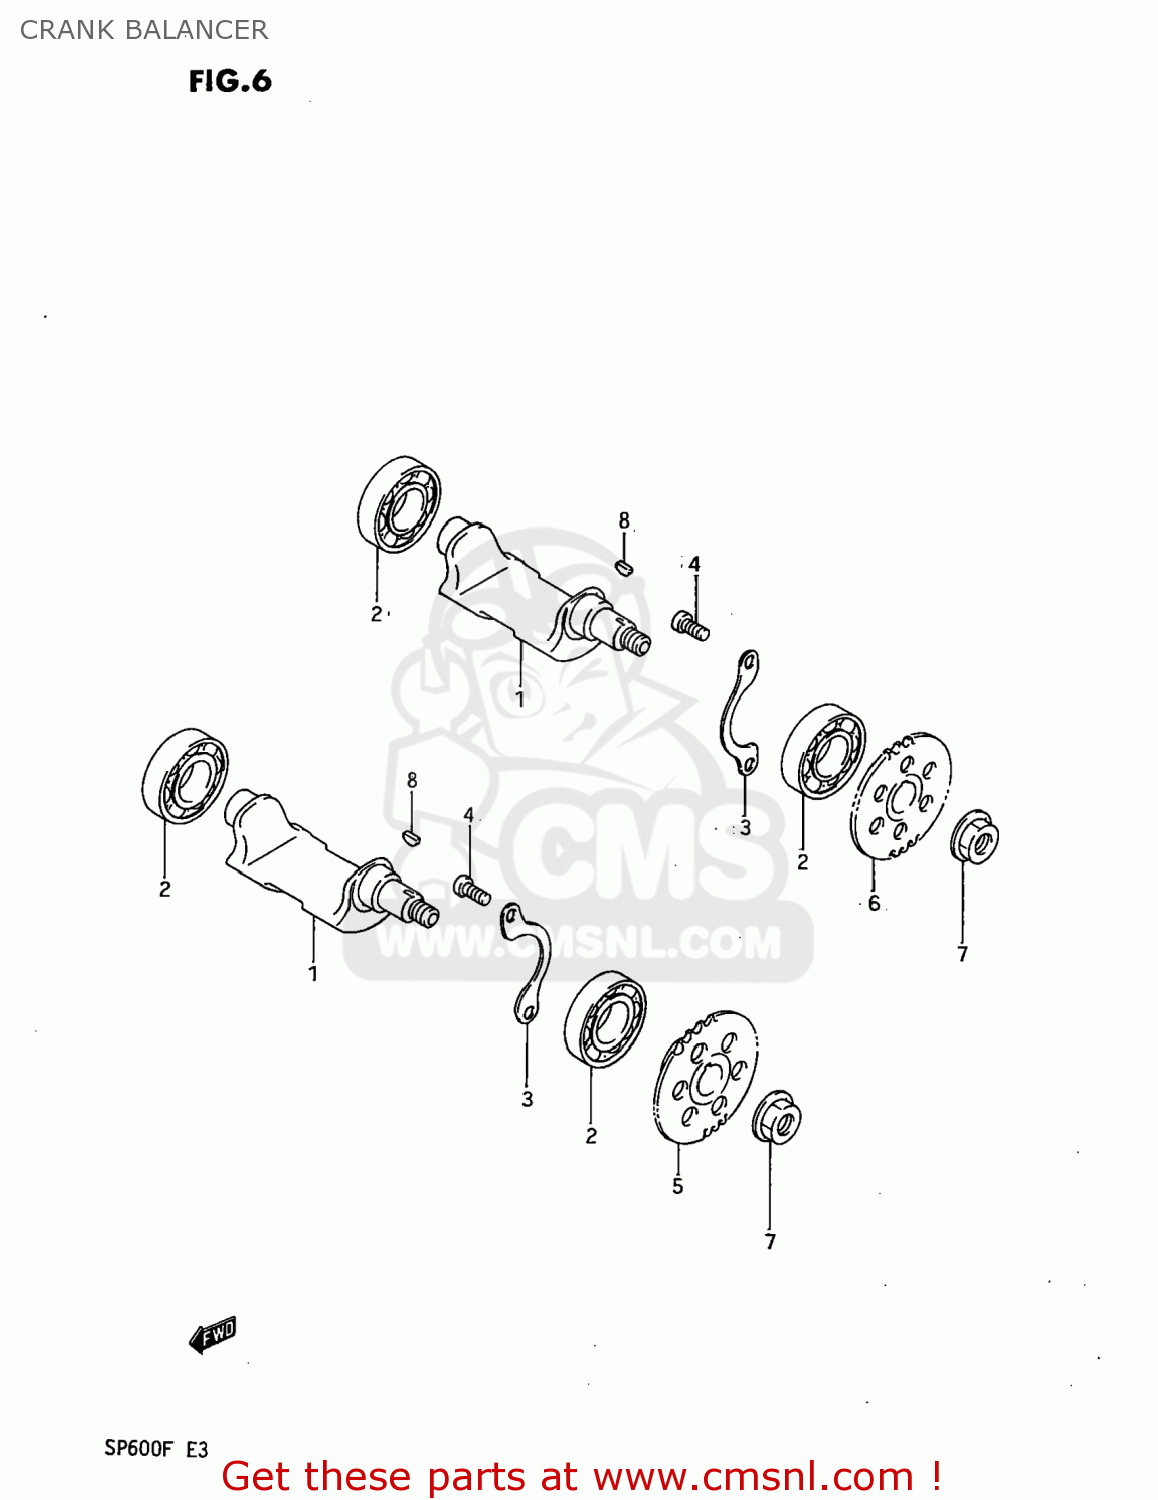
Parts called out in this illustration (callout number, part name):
1	BALANCER,CRANKSHAFT
2	BEARING
3	RETAINER,CRANK BAL BEARING
4	SCREW
5	SPROCKET,BALANCER DRIVE
6	SPROCKET,BALANCER DRIVE
7	NUT
8	KEY
